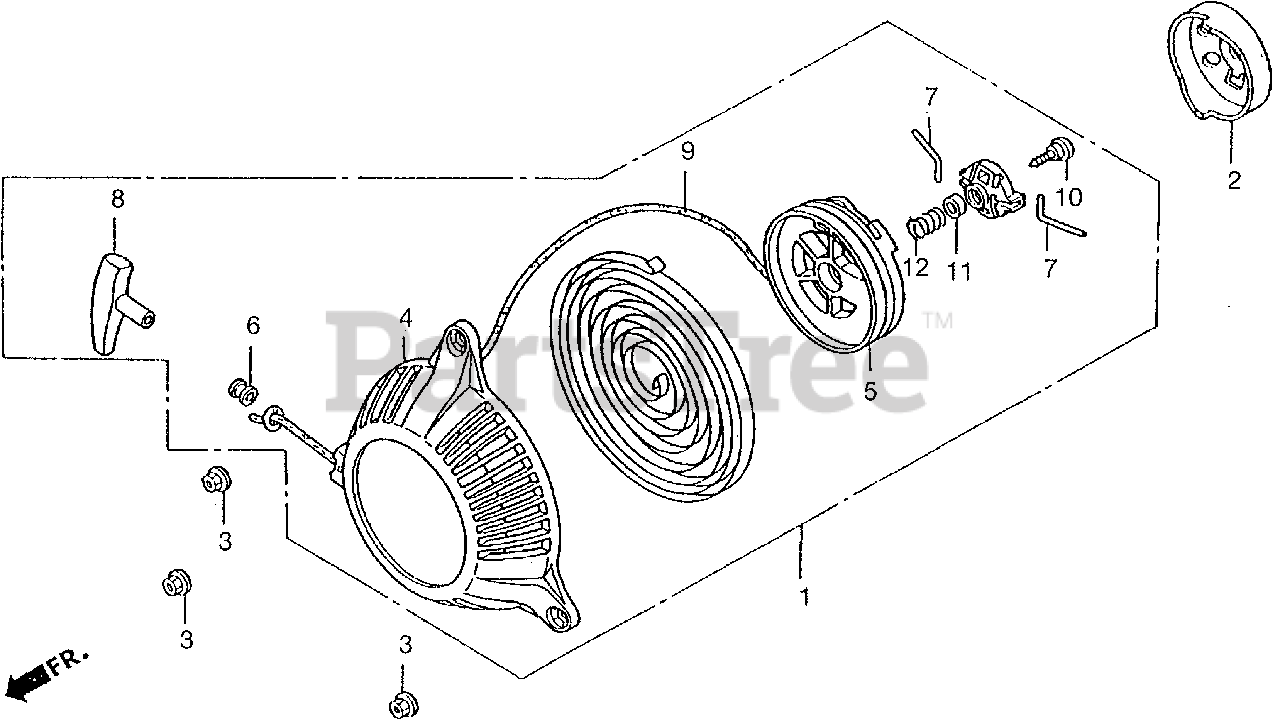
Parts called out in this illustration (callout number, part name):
1	STARTER ASSY., RECOIL
2	PULLEY, RECOIL STARTER
3	NUT, FLANGE (5MM)
4	CASE, RECOIL STARTER
5	REEL, RECOIL STARTER
6	GUIDE, ROPE
7	SWINGARM
8	KNOB, RECOIL STARTER
9	ROPE, RECOIL STARTER
10	SCREW, SETTING
11	COLLAR
12	SPRING, FRICTION
